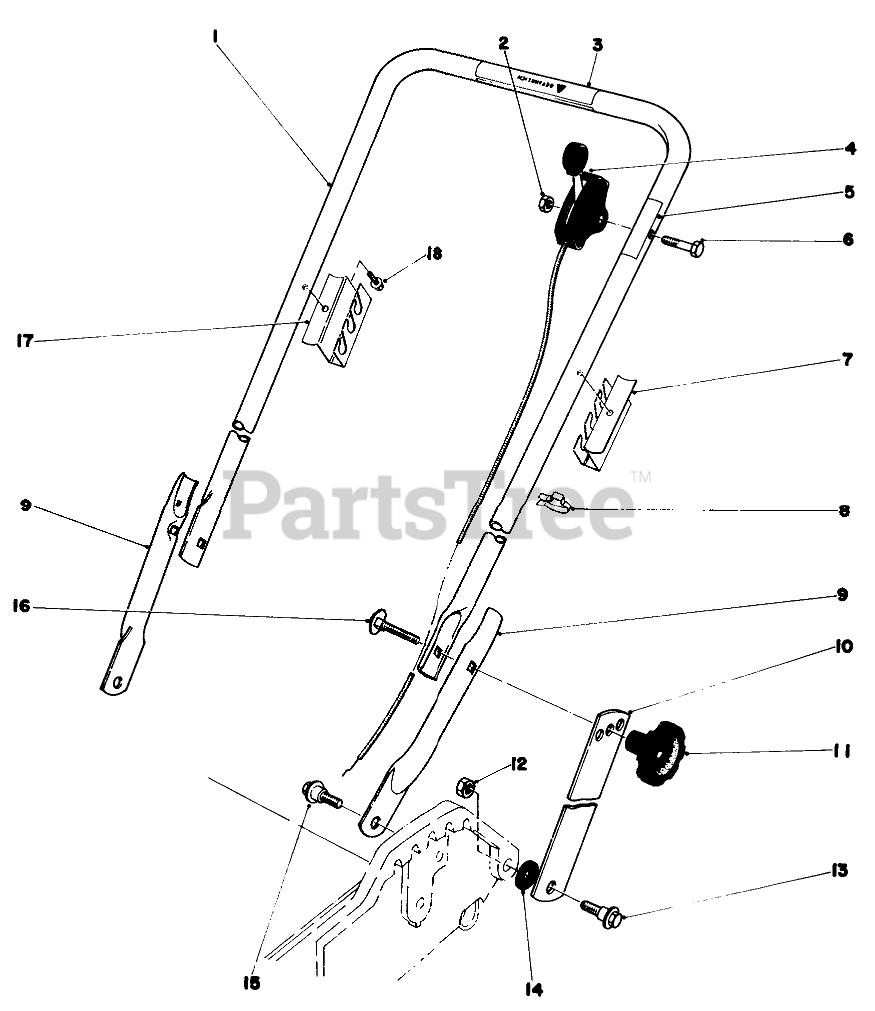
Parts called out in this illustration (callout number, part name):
1	Handle-Upper
2	NUT-LOCK
3	Decal Danger
4	Throttle Control
5	Decal-Throttle
6	SCREW-HH
7	SUPPORT BAG LH
8	BOWDEN CLIP
9	Hand-Lower
10	18" HANDLE LATCH
12	Nut
13	SCREW-SHOULDER
14	SPACER
15	SCREW-SHOULDER
16	SCREW-HANDLE
17	SUPPORT BAG RH
18	SCREW-HWHTF
